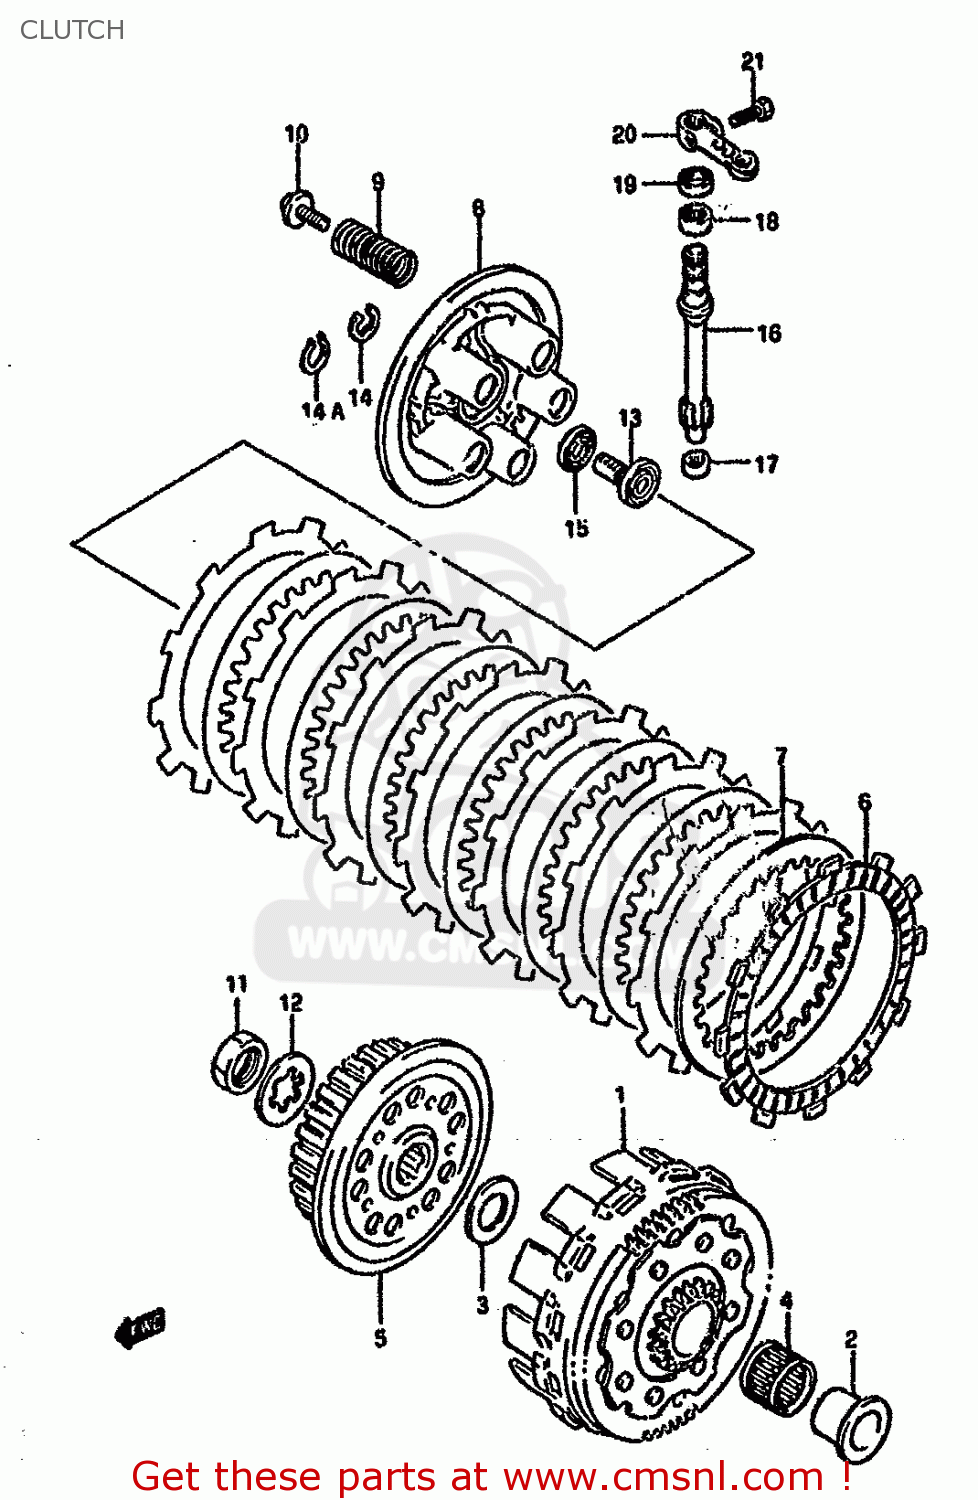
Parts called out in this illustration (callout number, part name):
1	GEAR ASSEMBLY,PRIMARY DRIVE
2	SPACER,PRIMARY DRIVEN
3	WASHER
4	BEARING(25X30X22)
5	HUB,CLUTCH SLEEVE
6	PLATE,CLUTCH DRIVE(T:2.8) (NAS)
7	PLATE,CLUTCH DRIVEN(T:1.4) (NAS)
8	DISC,CLUTCH PRESSURE
9	SPRING
10	BOLT(5X25)
11	NUT (20MM)
12	WASHER,LOCK
13	RACK,CLUTCH RELEASE
14	E RING
14A	CIRCLIP,10MM
15	BEARING(10X22X2.8)
16	PINION,CLUTCH RELEASE(NT:12)
17	BEARING(9X13X10)
18	BEARING(12X16X10)
19	SEAL,OIL(10X17X5)
20	ARM,CLUTCH RELEASE
21	BOLT
